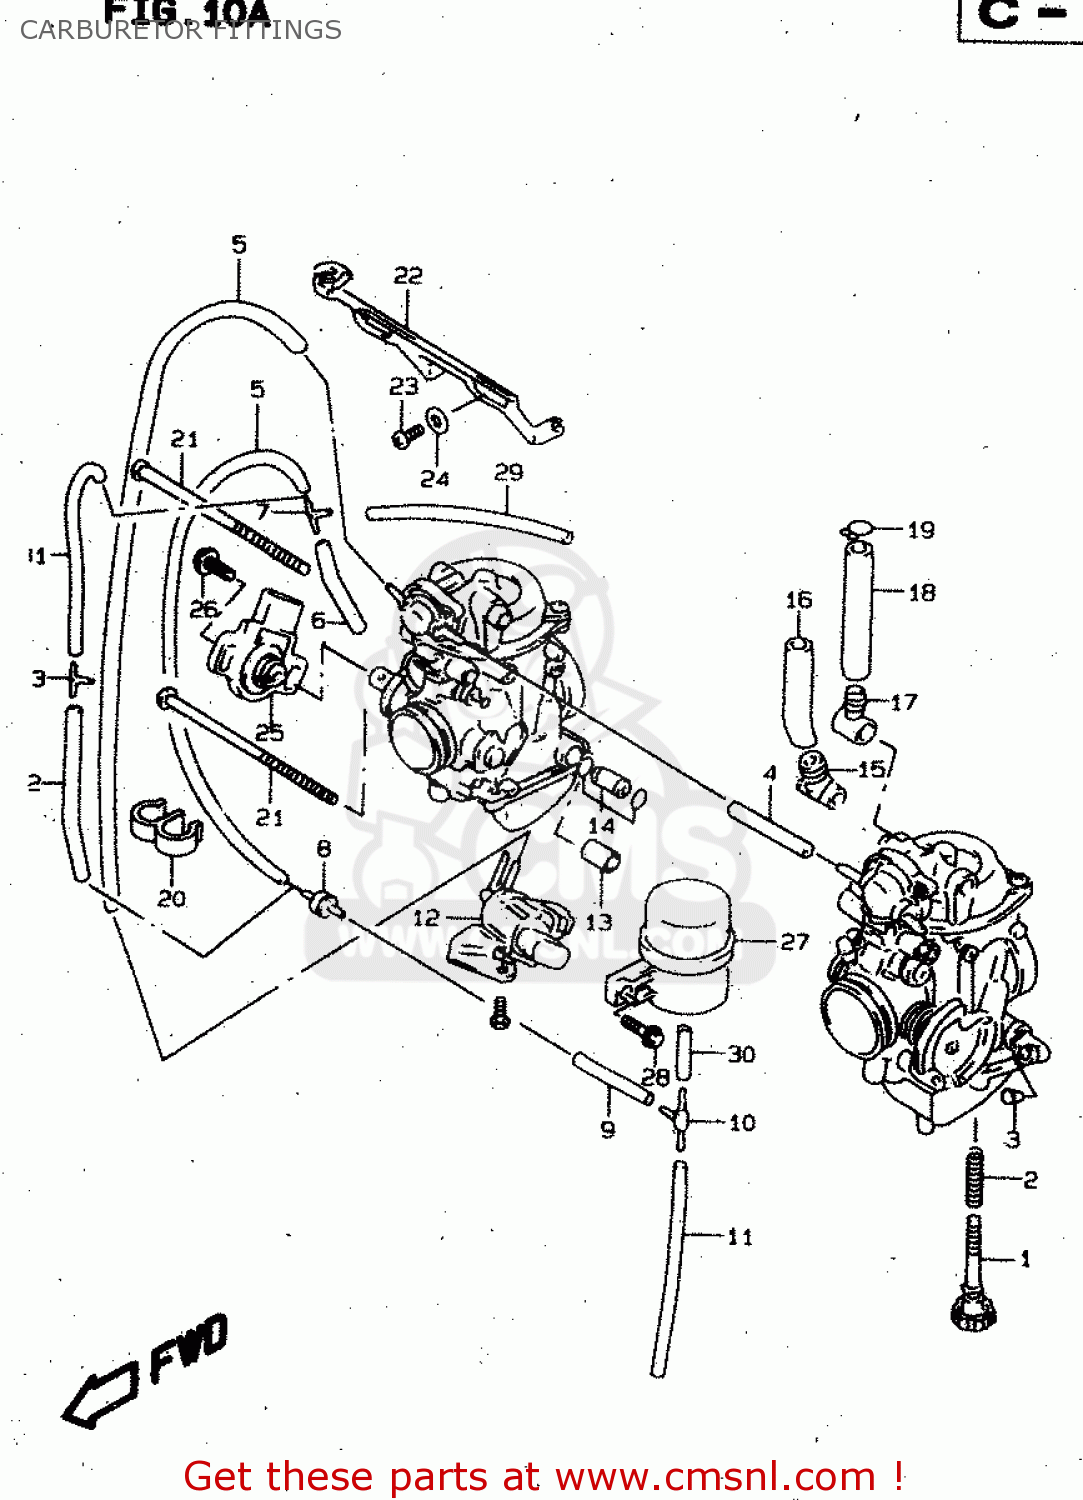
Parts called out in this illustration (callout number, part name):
1	ADJUSTER
2	SPRING
3	FILTER
4	HOSE (3.2X7.4X45)
5	HOSE
6	HOSE (3.2X7.4X50)
7	NIPPLE
8	VALVE,CHECK
9	HOSE
10	3 WAY
11	HOSE (3.2X7.4X200)
12	VALVE ASSY,3WAY SOLENOID
13	PIPE
14	PIPE
15	HOSE
16	HOSE(7X12.1X600)
17	3 WAY
18	HOSE
19	CLIP
20	CLAMP
21	SCREW(6X100)
22	LEVER
23	SCREW
24	PACKING
25	SENSOR ASSY,THROTTLE
26	SCREW, SENSOR
27	CHAMBER,VACUUM
28	BOLT
29	HOSE(5X10X600)
30	HOSE(3.5X7.5X600)
31	HOSE
32	HOSE
33	3 WAY
